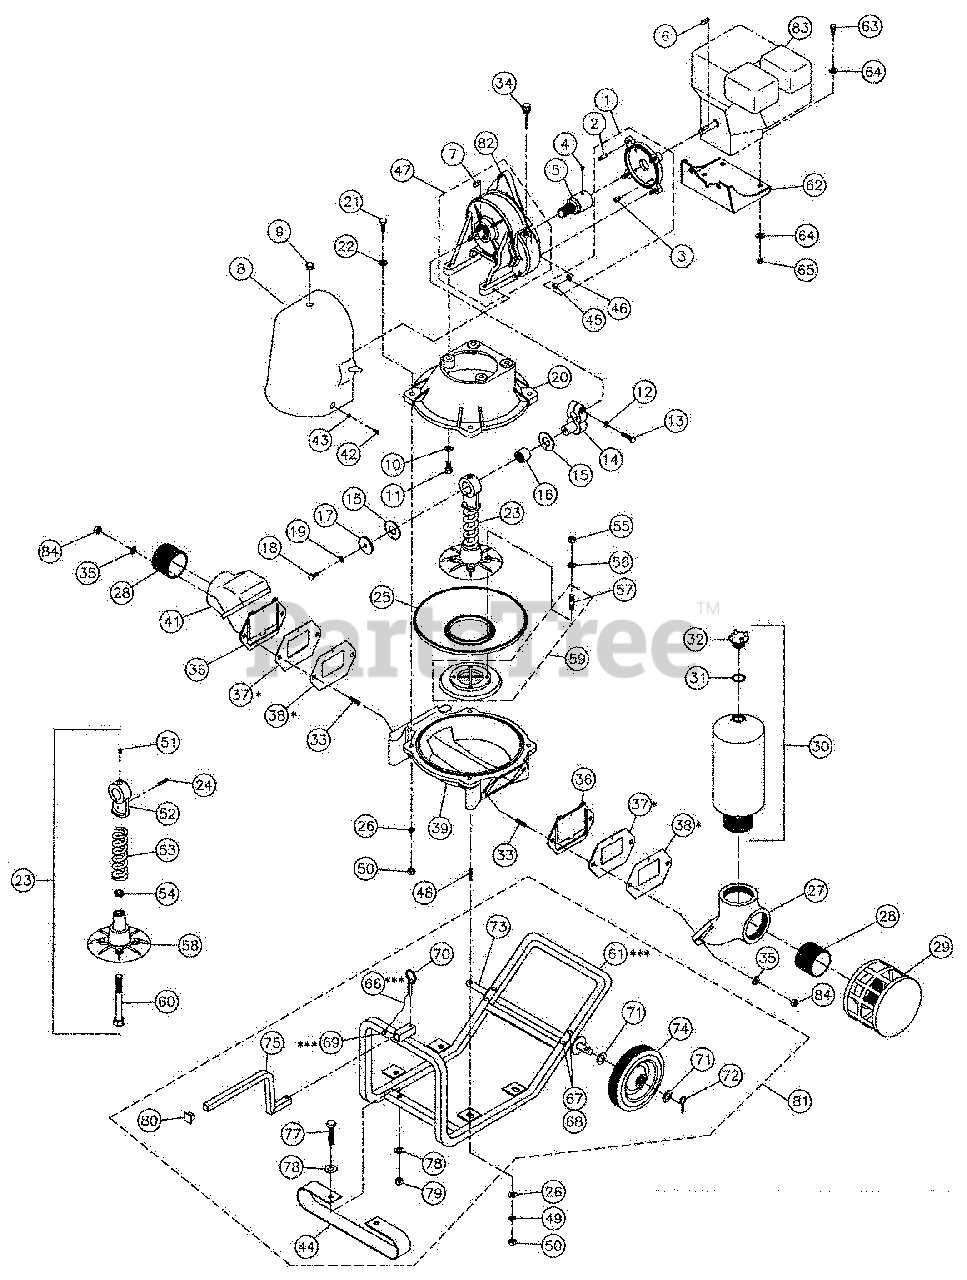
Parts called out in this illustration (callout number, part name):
1	ADAPTER, ENGINE
3	SCREW, ALLEN
4	SCREW SET (8MX1.25X10)
5	PINION (HELICAL 1:43)
6	KEY STOCK (3/16X1)
8	COVER *R1* (RED)
9	PLUG, COVER (#35)
10	WASHER, PLAIN (12MM)
11	BOLT, HEX.
12	WASHER, SPRING (10MM)
13	BOLT, HEX.
14	CRANK (3" PUMP)
15	WASHER, FIBER
16	BEARING, CRANK
17	COVER, CONNECTING ROD BUSHING
18	BOLT, HEX.
19	WASHER, SPRING (10MM)
20	CASE, MOUNTING (UPPER) (ALUMINUM)
21	BOLT, HEX.
22	WASHER, PLAIN (12MM)
23	ROD, CONNECTING
25	DIAPHRAGM, NEOPRENE
26	WASHER, PLAIN (12MM)
27	PORT, SUCTION NPT (3")
28	NIPPLE, FACED (3")
29	STRAINER, TRASH SQ. HOLE (3")
30	CHAMBER, AIR NPT (3")
31	O-RING, AIR CHAMBER PLUG
32	PLUG, AIR CHAMBER (BRONZE)
34	DIPSTICK, OIL W/DISCHARGE VALVE
35	WASHER, PLAIN (12MM)
36	CLAPPET, NEOPRENE
37	WEARPLATE, STAINLESS STEEL
38	GASKET, WEARPLATE PAPER
39	CASE (LOWER) (ALUMINUM)
41	PORT, DISCHARGE (3")
42	BOLT, HEX. (8x1.25x15)
43	WASHER, PLAIN (8MM)
44	SPRING, FRAME
46	WASHER, SPRING (10MM)
47	GEAR BOX, HELICAL (3D) (1:43 SILENT)
49	WASHER, STAR (12MM)
51	NIPPLE, GREASE
52	ROD END (UPPER)
53	SPRING, CONNECTING ROD
54	RING (INNER)
56	WASHER, PLAIN (12MM)
57	STUD (12X1.75-70)
58	ROD END (LOWER)
59	FLANGE, CONNECTING ROD
60	BOLT, SPECIAL
61	FRAME ASSY., WHEEL
62	BRACKET, ENGINE MOUNTING
63	BOLT, HEX. (5/16-18X1.5")
64	WASHER, FLAT (5/16" SAE)
65	NUT, NYLOCK (5/16"-18) (N/A: PURCHASE STD. HARDWARE)
66	CABLE, KEY
67	BOLT, HEX. (5/16-18X1.5")
68	NUT, NYLOCK (5/16"-18) (N/A: PURCHASE STD. HARDWARE)
70	PIN, QUICK RELEASE
71	WASHER, PLAIN (20MM)
72	PIN, SPLIT (4.0X30)
73	SHAFT, AXLE
74	WHEEL (GLEASON 10"X2.75"=254X70)
77	BOLT (3/8X1-3/4) (N/A: PURCHASE STD. HARDWARE)
78	WASHER (3/8") (N/A: PURCHASE STD. HARDWARE)
79	LOCKNUT, NYLOCK (3/8"-16) (N/A: PURCHASE STD. HARDWARE)
80	PLUG, HANDLE CAP
